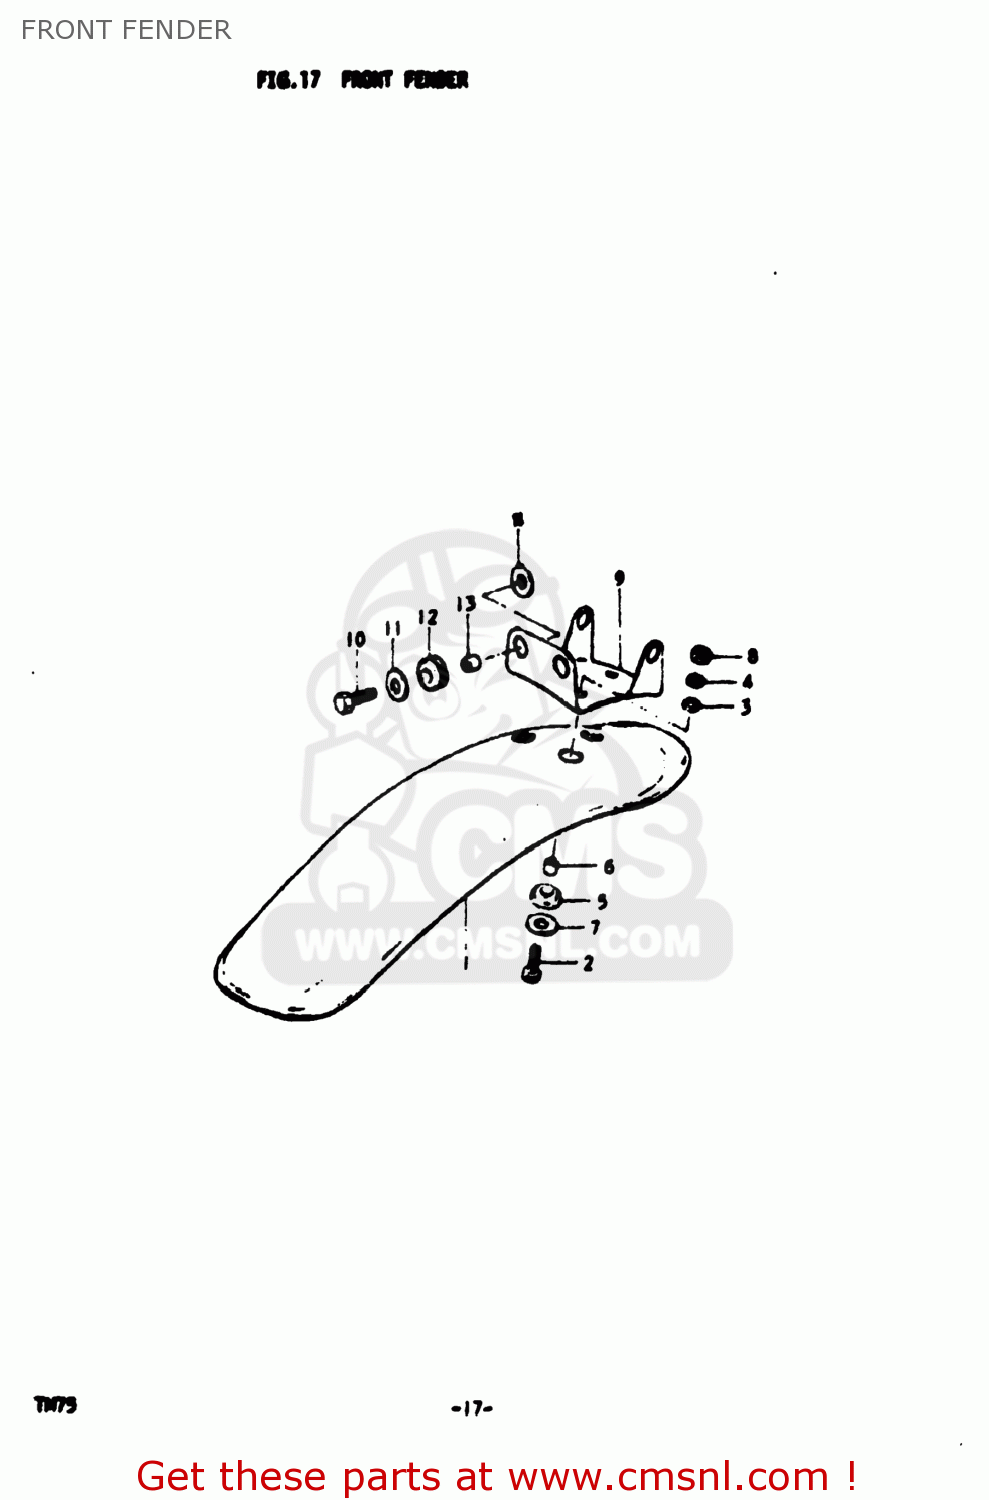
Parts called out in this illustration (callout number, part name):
1	FENDER,FRONT
2	BOLT(6X18)
3	WASHER
4	LOCK WASHER
5	CUSHION
6	SPACER
7	WASHER (6.5X20X1.2)
8	NUT
9	BRACE,FRONT FENDER
10	BOLT(6X18)
11	WASHER (6.5X20X1.2)
12	CUSHION
13	SPACER (7X9X7)
